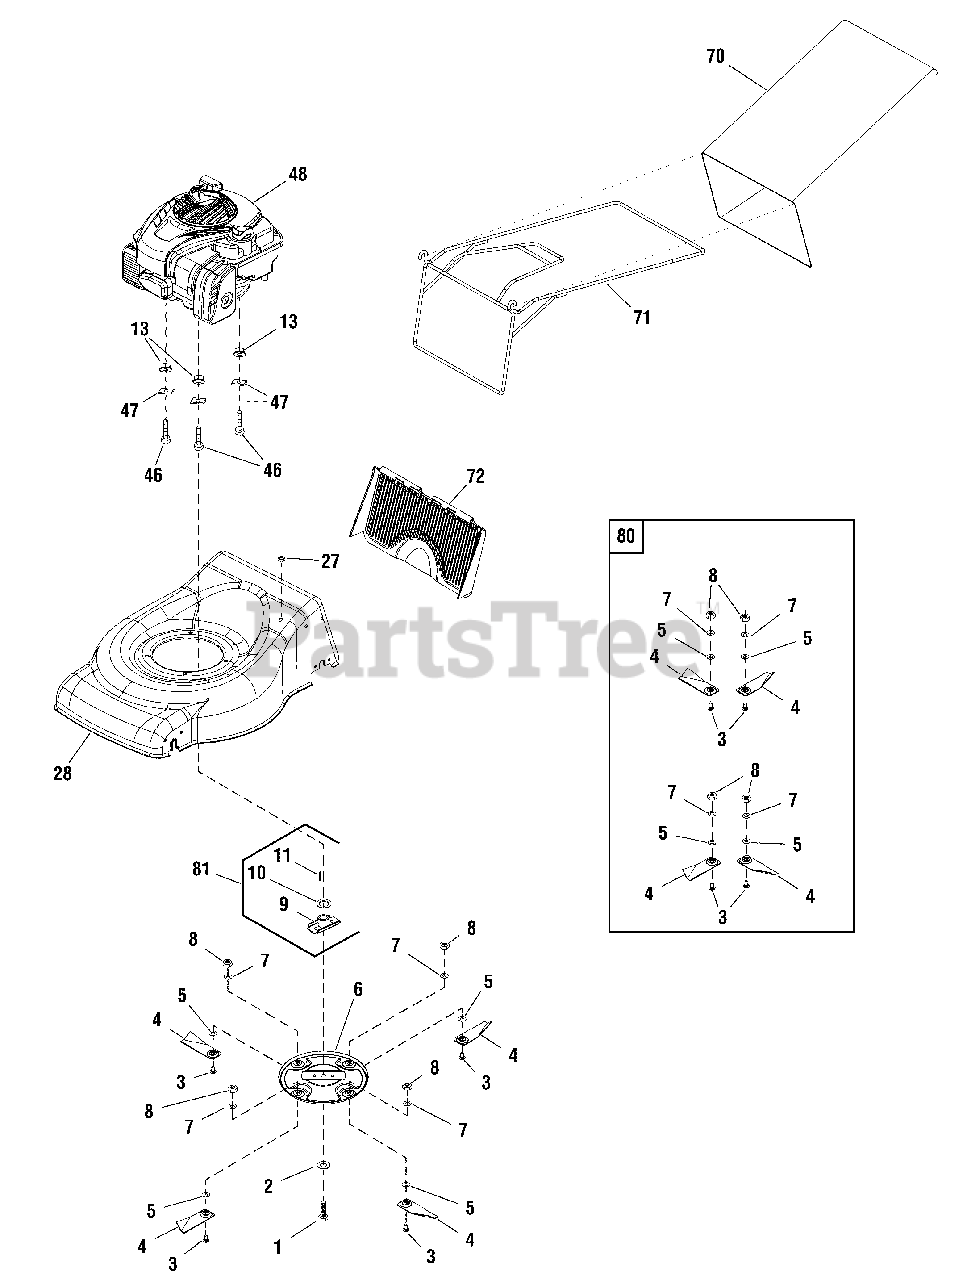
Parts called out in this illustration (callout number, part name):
1	BOLT, Blade
3	BOLT, Blade
5	WASHER, Blade
6	BLADE DISC
7	* WASHER, Flat
8	* NUT, Hex Lock
9	SUPPORT, Blade
10	SLEEVE, Blade Support
13	* NUT, Hex Lock
27	GROMMET
46	* BOLT, Hex
47	WASHER, Square
48	** ENGINE, Briggs & Stratton 450E Series
70	BAG, Grass
72	COVER, Rear
80	KIT, Blade
81	KIT, Blade Adapter
